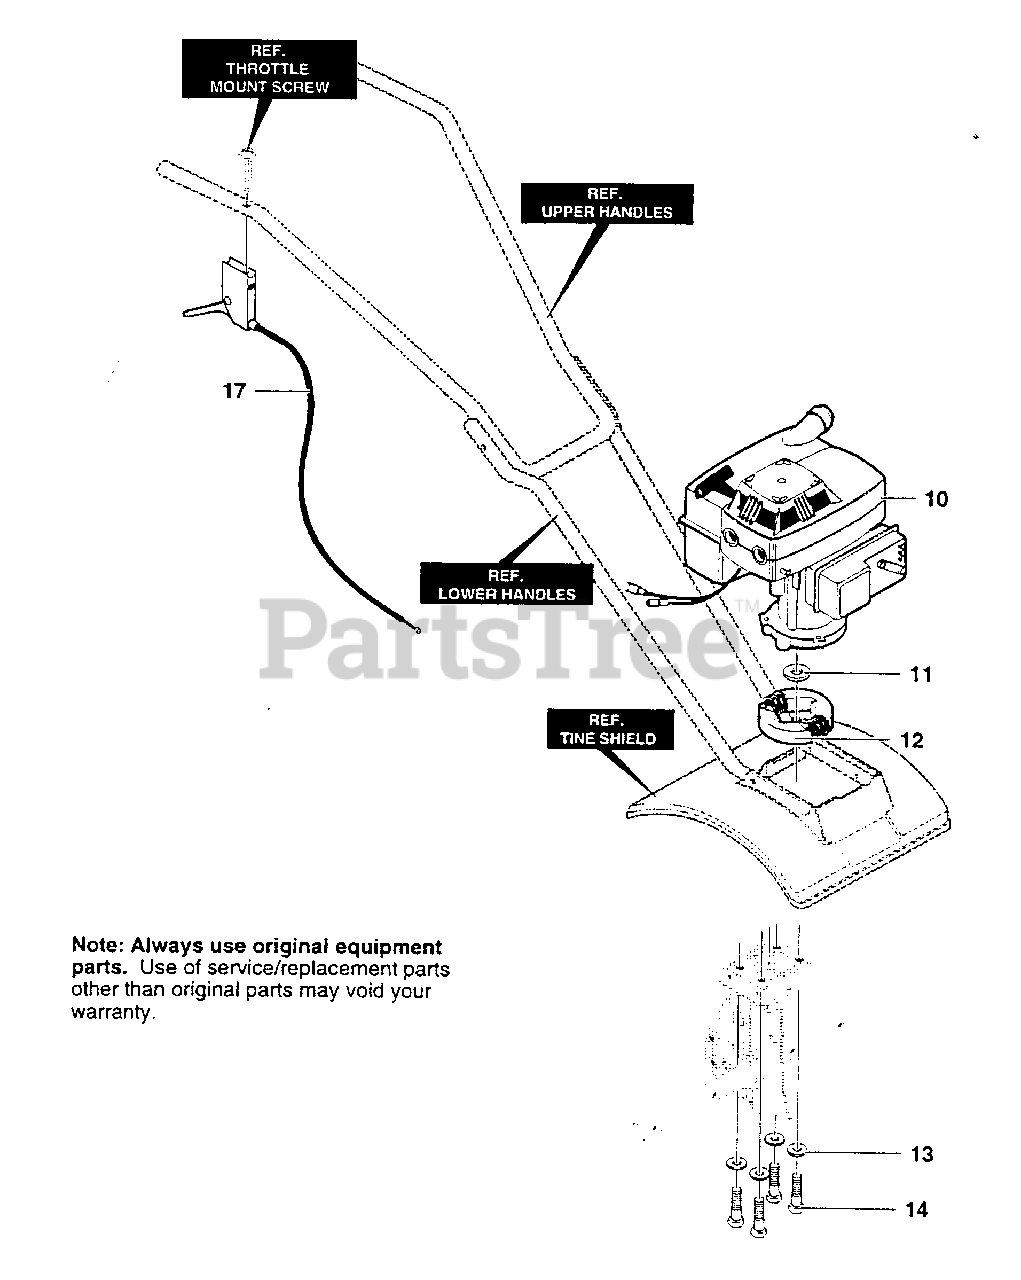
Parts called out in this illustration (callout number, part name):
11	WASHER, FLAT .378 X 1.25X.06
12	ROTOR (SMALLER DIA.)
13	WASHER, REGSPTLK.263 X .49X.07
14	SCREW, 1/4-20 X 1.75 HHC
17	CABLE, THROTTLE, CULTIVATOR
17	MANUAL, OWNERS
